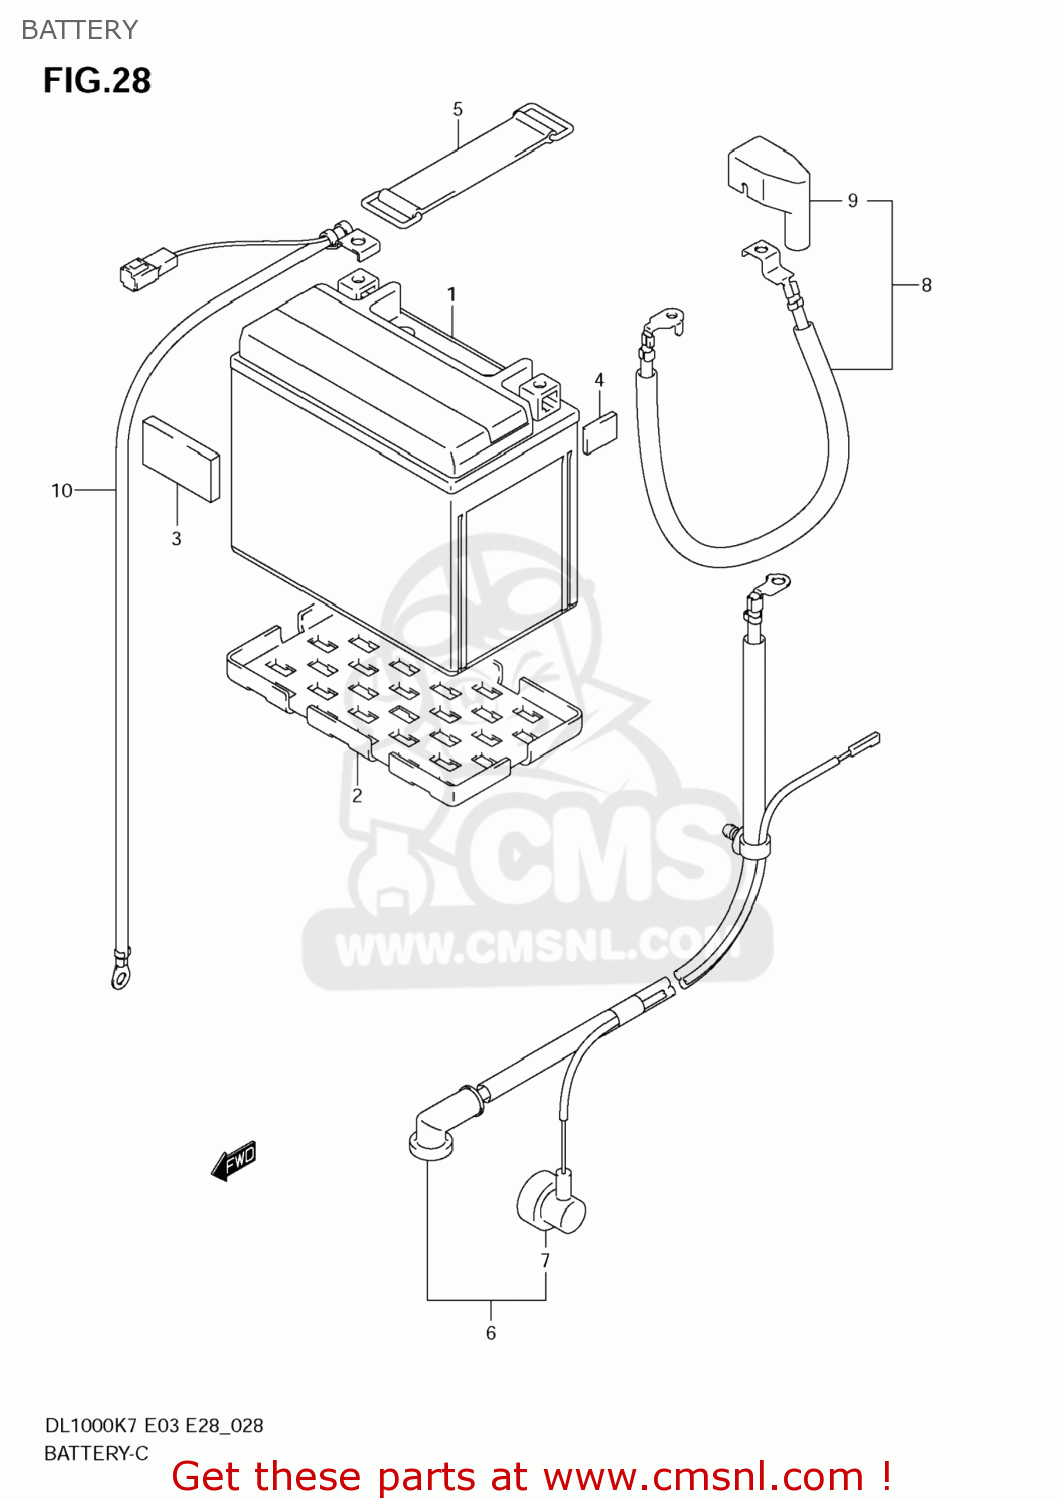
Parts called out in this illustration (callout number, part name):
1	BATTERY ASSY (12V) YTX14-BS
2	PROTECTOR,BATTERY
3	PROTECTOR,BATTERY(70X100X6)
4	PROTECTOR(170X95X3.0)
5	BAND
6	WIRE,STARTER MOTOR LEAD
7	CAP,OIL PRESSURE SWITCH
8	WIRE,BATTERY PLUS LEAD
9	CAP,BATTERY PLUS LEAD
10	WIRE,BATTERY MINUS LEAD
